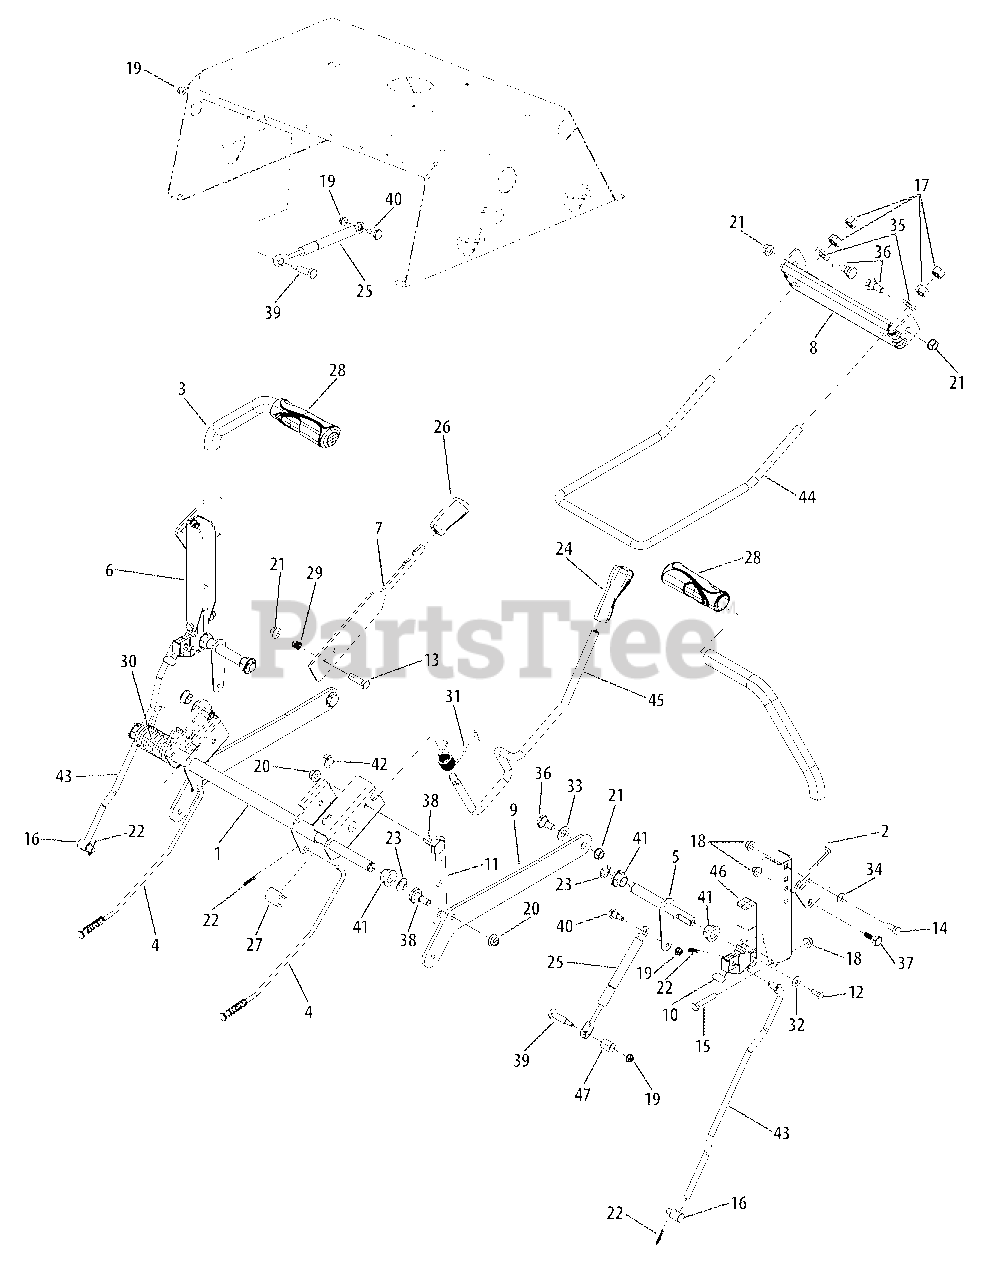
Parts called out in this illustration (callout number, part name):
4	Brake Rod Assembly
5	Shaft Control
6	Lapbar Pivot Bracket
10	Actuater Bracket
12	Hex Lock Screw, 1/4-20 x .625
13	Hex Screw, 3/8 -16 x 1.25
14	Hex Screw, 5/16-18 x .75
15	Hex Screw, 5/16-18 x 1.75
16	Ferrule, 3/8 -24 x .375
17	Hex Nut, 1/2-13
18	Flange Lock Nut, 5/16-18
19	Flange Lock Nut, 1/4-20
20	Flange Lock Nut, 3/8 -16
21	Flange Lock Nut, 3/8 -16
22	Cotter Pin, 1.13
23	E-Ring, .625
24	Handle Grip, 1/2
25	Damper Cylinder
26	Handle Grip
27	Spacer, .62 x 1.00
28	Handle Grip, 1.0
29	Compression Spring, .50 x .50
30	Torsion Spring, 1.194
31	Spring, Torsion RZT
32	Bell Washer, .265 x .75 x .062
33	Flat Washer, .510 x 1.00 x .060
34	Flat Washer, .344 x .688 x .065
35	Flat Washer, .531 x 1.062 x .134
36	Shoulder Bolt, .496 x .336 x 3/8 -16
37	Shoulder Screw, .437 x .268 x 5/16-18
38	Shoulder Screw, .500 x .434
39	Shoulder Screw, .374 x 1.16
40	Shoulder Screw, .375 x .380 x 1/4-20
41	Hex Flange Bearing
42	Flange Bearing, .626 x .938 x .344
43	Lapbar Control Rod
44	Deck Front Hanger Rod
45	Deck Lift Handle Rod
47	Spacer, .385 x .630 x .75
